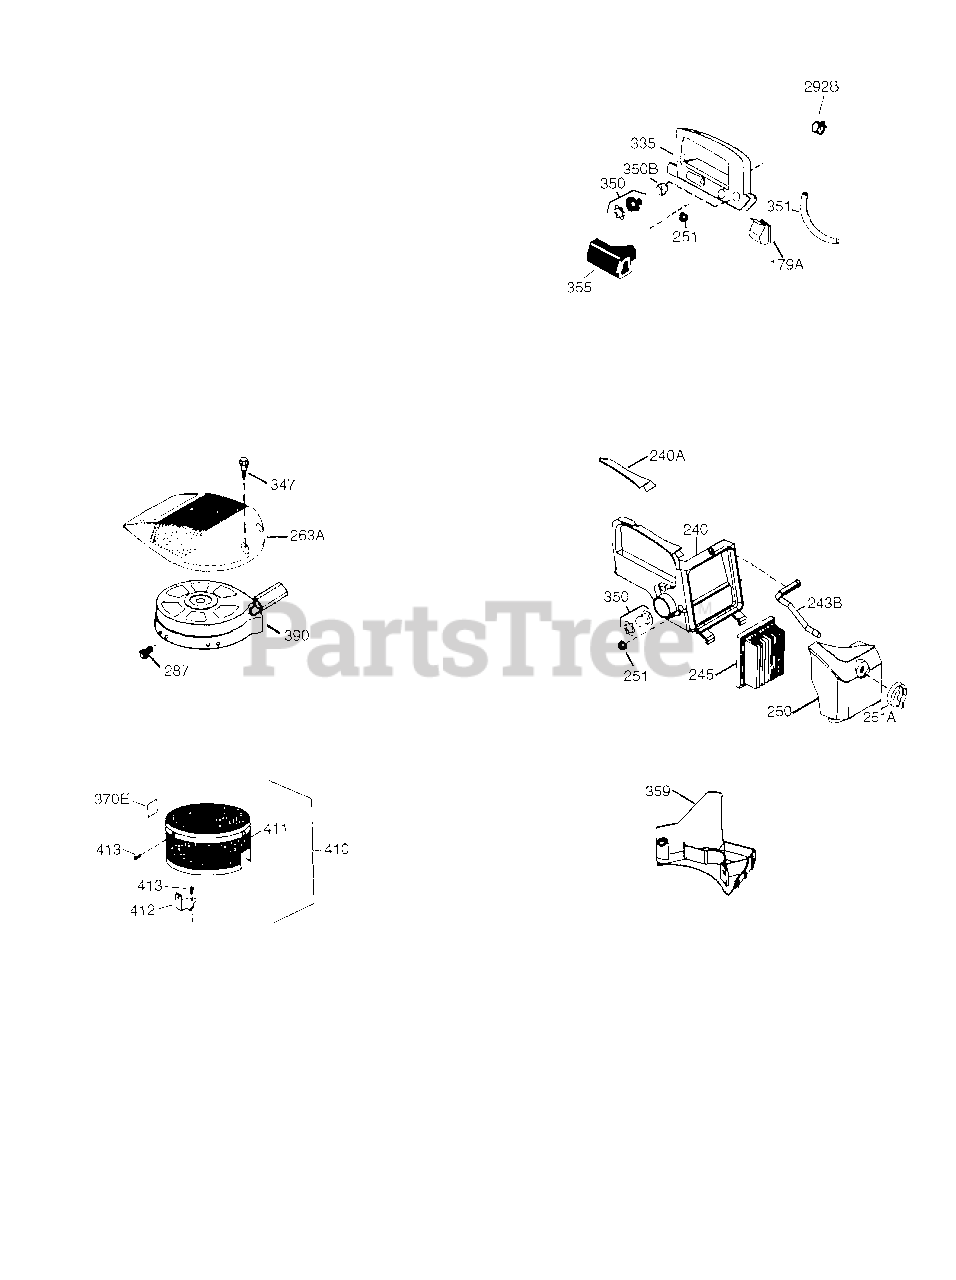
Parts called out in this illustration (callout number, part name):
187B	* Carburetor Gasket/Air Baffle
240	Air Cleaner Body (Incl.239,299 & 350)
245	Air Filter (Paper) (also available in Packaged Part #740031B for model VLV only) (also available in Packaged Pa rt #740061C for model OH195)
250	Air Cleaner Cover
251	Lock Nut 1/4-20
263A	Starter Grill
287	Screw, 8-32 x 21/64"
347	Screw, 10-32 x 27/32"
350	Primer
390	Rewind Starter NOTE: This engine cou ld hav e been built with 590739 start er. Refer to the design of the rope p ulley strength ribs for part identifi cation. Individual starter parts do not interchange.
999	Summer Maintenance Kit (incl. Oil, Sp ark Plug, Air Cleaner, & Ultra Fresh)
